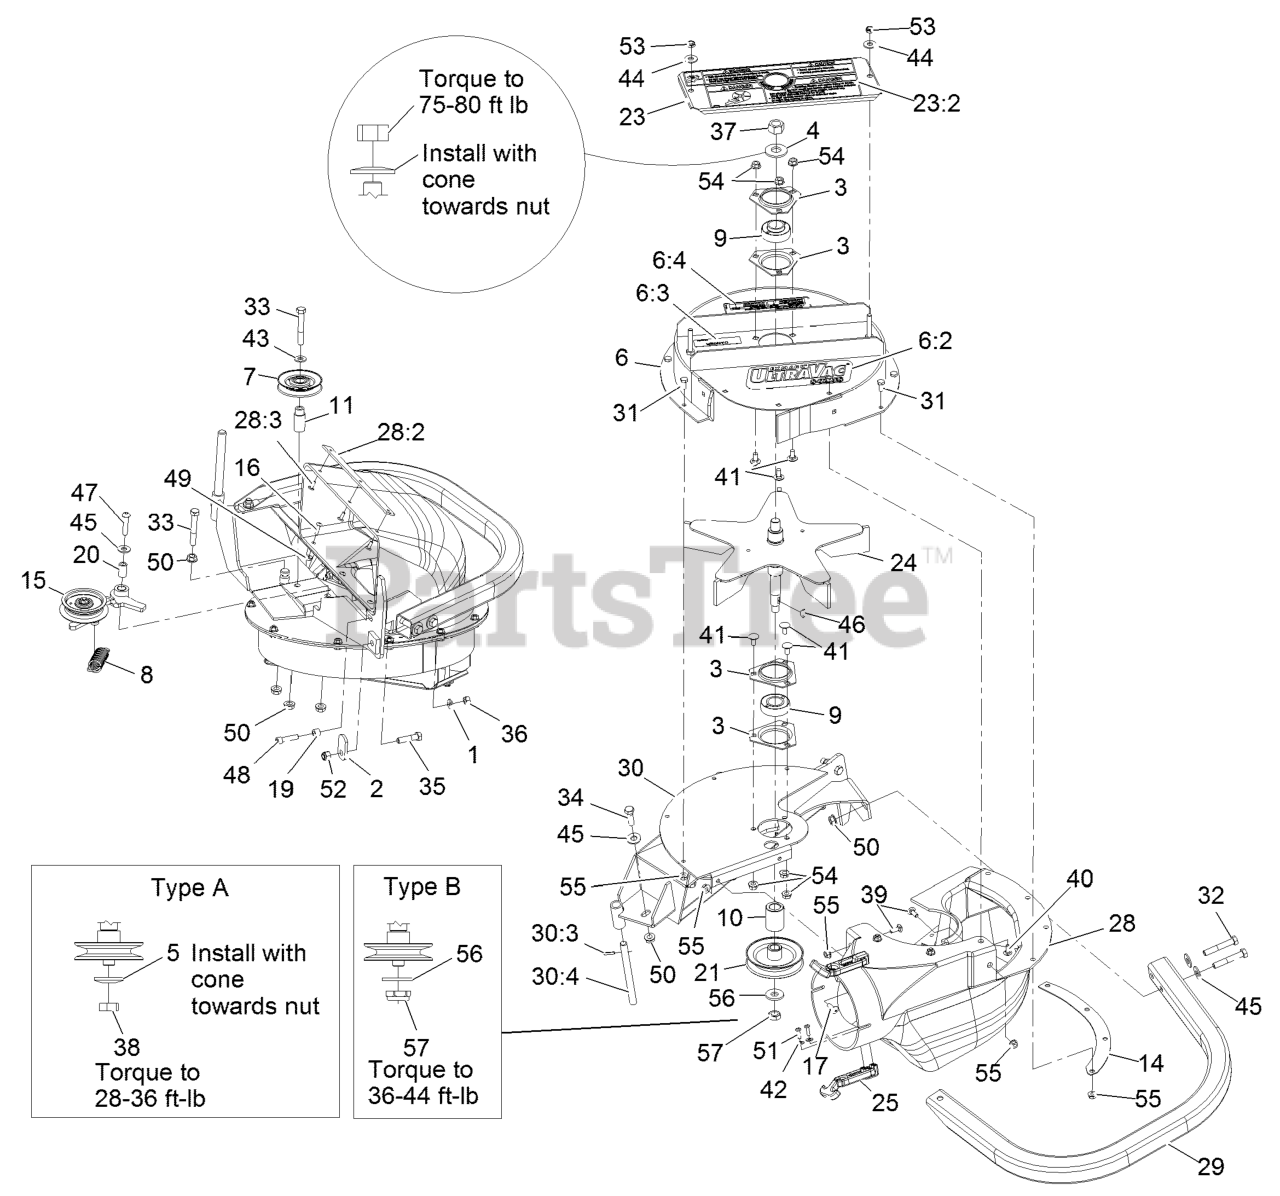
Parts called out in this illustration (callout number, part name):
1	WASHER-SPRING
2	LATCH-CATCHER, GRASS
3	HOUSING-FLANGE
4	WASHER-SPRING
5	WASHER-SPRING
6	ASM-UPPER HOUSING SMALL
6:2	DECAL-ULTRA VAC S-SERIES
6:3	DECAL-COVER, MISSING
6:4	DECAL,WEIGHT
7	IDLER-INSIDE
8	SPRING-IDLER
9	BEARING
14	PLATE-BACKING, BLOWER
15	Asm, Idler
16	SCREW-HEAD, TRUSS
19	BUSHING, LOCATOR
20	BUSHING-PIVOT, IDLER
21	SHEAVE-BLOWER
23	ASM, BEARING COVER
23:2	DECAL-WARNING
24	IMPELLER
25	LATCH-RUBBER
28	ASM,BLOWER CHUTE LHP
28:2	PLATE-REINFORCEMENT
28:3	RIVET-BLIND
30	WELD, FRAME SM BLOWER
30:3	PIN-ROLL
30:4	SHAFT-CATCHER, GRASS
31	SCREW-HH
32	SCREW-HH
33	BOLT-CARR
34	SCREW-HH
35	SCREW-HH
36	NUT-HEX
37	NUT-HEX
38	NUT-JAM
39	BOLT-CARR
40	SCREW-CARR
41	SCREW-CARR
42	WASHER-FLAT
43	WASHER-FLAT
44	WASHER-FLAT
45	WASHER-FLAT
46	KEY-WOODRUFF
47	SCREW-HSBH
48	SCREW-HSH
50	NUT-HHF, WHIZ
51	SCREW-PPH
52	NUT-LOCK, NI
53	NUT-LOCK, NI
56	WASHER-FLAT
57	NUT-LOCK, NI
